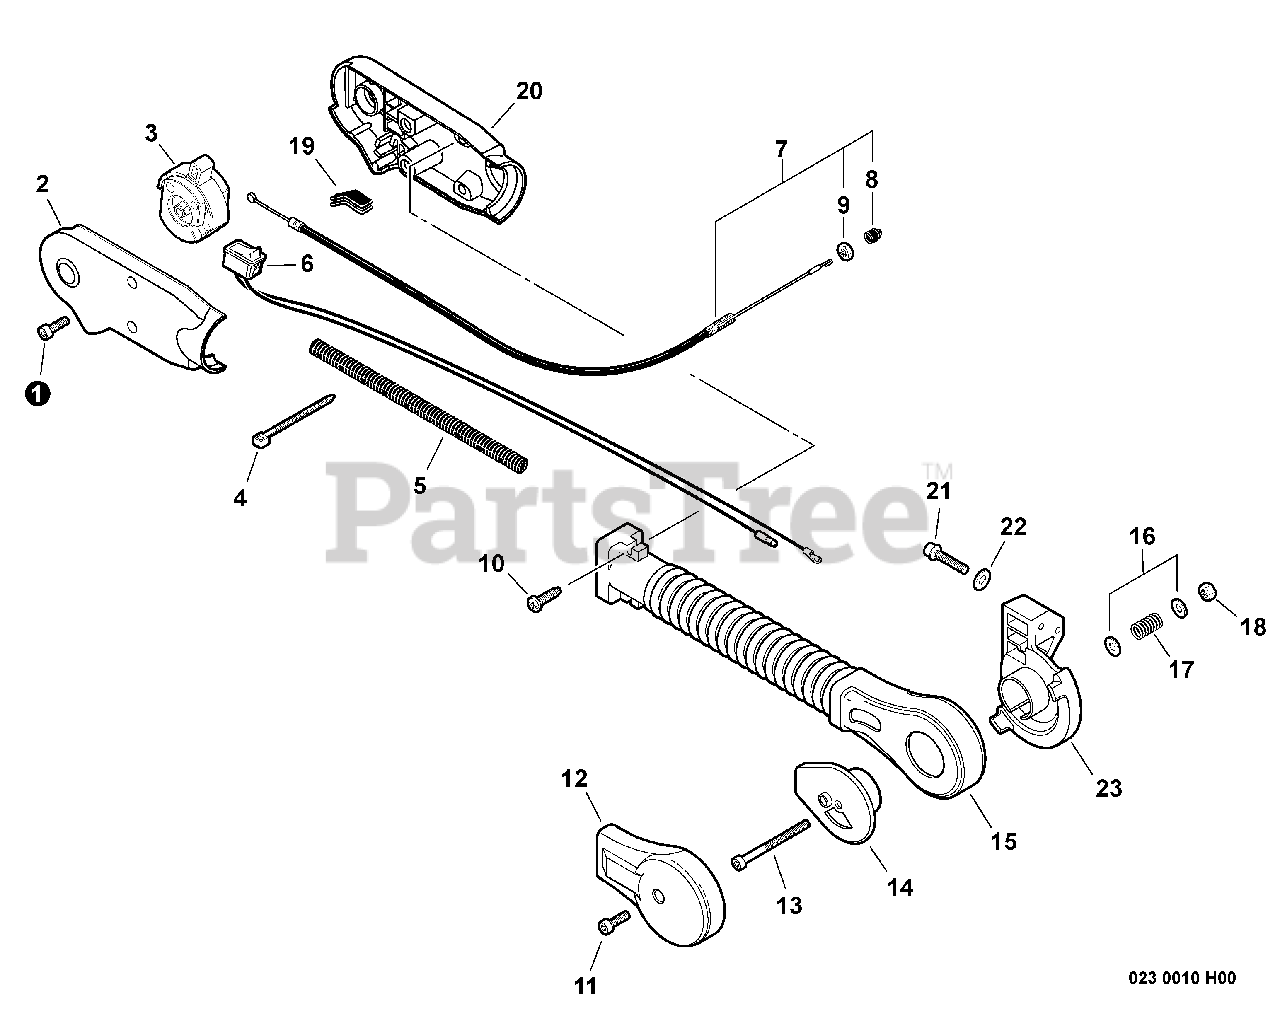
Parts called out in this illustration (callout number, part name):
1	SCREW - 5X14
2	HANDLE, CONTROL - LEFT
3	THROTTLE CONTROL ASSY
4	TIE, CABLE - SMALL
5	TUBE, PROTECTIVE - CORRUGATED
6	IGNITION SWITCH ASSY
7	THROTTLE CABLE ASSY
8	CAP, DUST
9	LOCKNUT - 6
10	SCREW - 5X20
11	SCREW - 5X14
12	COVER, ARM
13	SCREW - 5X80
14	BRACKET, CONTROL ARM - OUTER
15	ARM, CONTROL
18	LOCKNUT - 5
20	HANDLE, CONTROL - RIGHT
21	SCREW - 5X25 -- TAPPING
22	WASHER - 5
23	BRACKET, ARM - INNER
